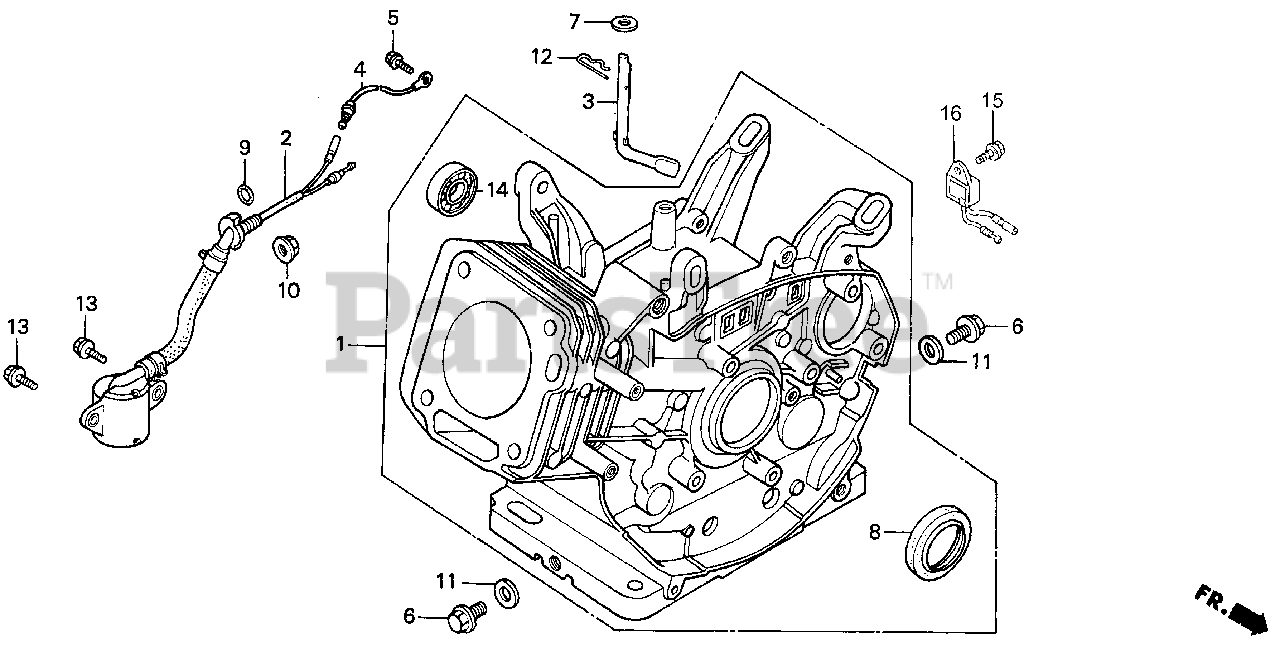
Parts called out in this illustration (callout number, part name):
1	CYLINDER ASSY. (BALANCER+ALERT)
2	SWITCH ASSY., OIL LEVEL
3	SHAFT, GOVERNOR ARM
4	SUB-HARNESS
5	BOLT, FLANGE (6X12) (CT200)
6	BOLT, DRAIN PLUG
7	WASHER (8.2X17X0.8)
8	OIL SEAL (30X46X8)
9	O-RING (13.5X1.5) (ARAI)
10	NUT, FLANGE (10MM)
11	WASHER, DRAIN PLUG (12MM)
12	PIN, LOCK (8MM)
12	PIN, LOCK (10MM)
13	BOLT, FLANGE (6X12)
14	BEARING, RADIAL BALL (6202)
